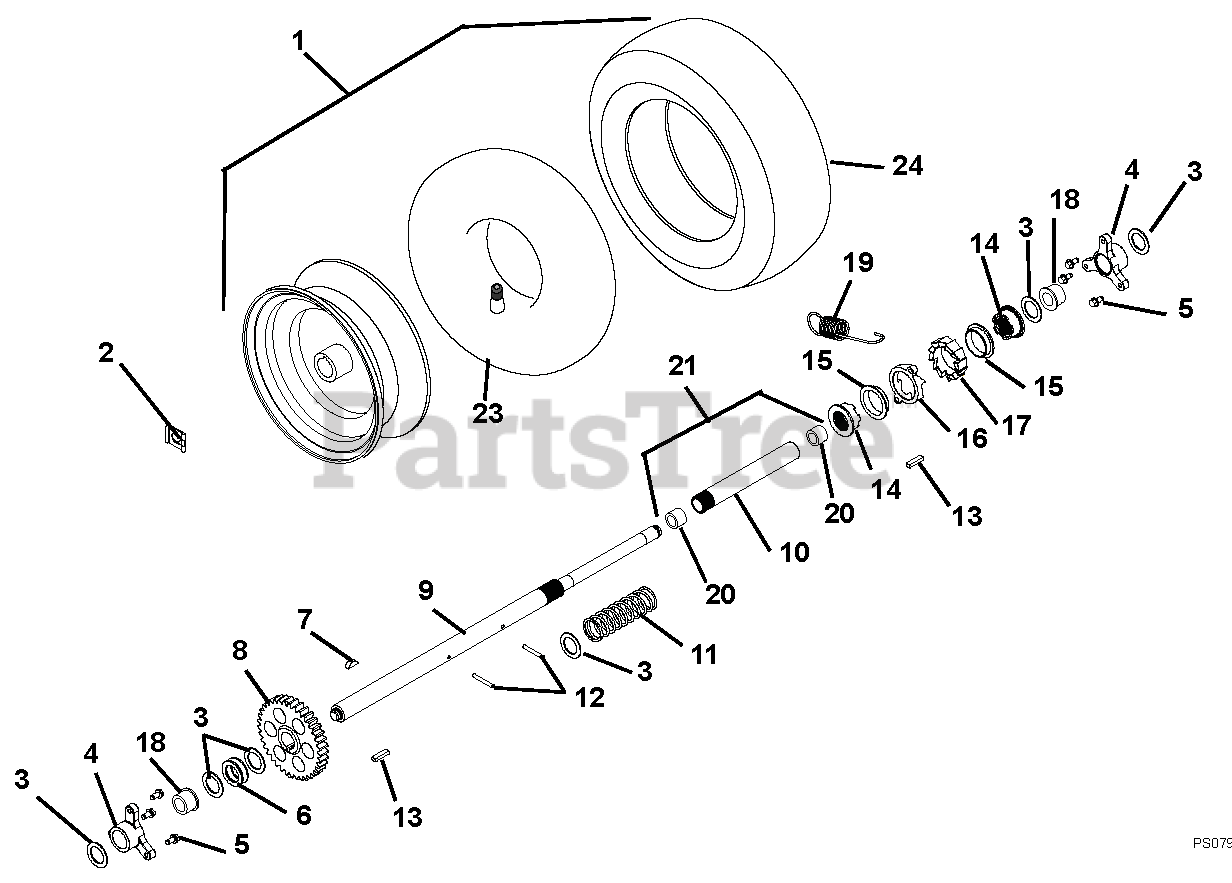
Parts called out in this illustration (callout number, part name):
1	TIRE/WHEEL, RH 16X6.50-8 DIFF
1	TIRE/WHEEL, LH 16X6.50-8 DIFF
2	CLIP, SNAP .625 DIA
3	WSHR-FL-STL 1.010X1.505X.062YZ
4	BUSHING, RAKE SHAFT 1"
5	@SCR-TAP .25-20X.50 HWH TR YWZ
6	SPACER 1.005X1.5075X.375
7	KEY-WDRF .25X.750X.313 SAE91
8	GEAR, SPUR
9	AXLE, DIFFERENTIAL-LONG
10	AXLE, DIFFERENTIAL-SHORT
11	SPRING, COMPRESSION
12	PIN-ROLL .188X1.50
13	KEY-RECT .25X.188X1.00
14	CLUTCH, DOG - SLIDING
15	BUSHING, FLANGE
16	GEAR, CLUTCH
17	GEAR, RATCHET
18	BSHG-FLG SPLIT NYLINER 1.0" HP
19	SG-TENS .06X.62X2.94
20	BSHG-SLV .706X.764X.75 BRZ
21	DECAL,FOOT
22	TUBE
23	TIRE, 16X6.50-8 K478
